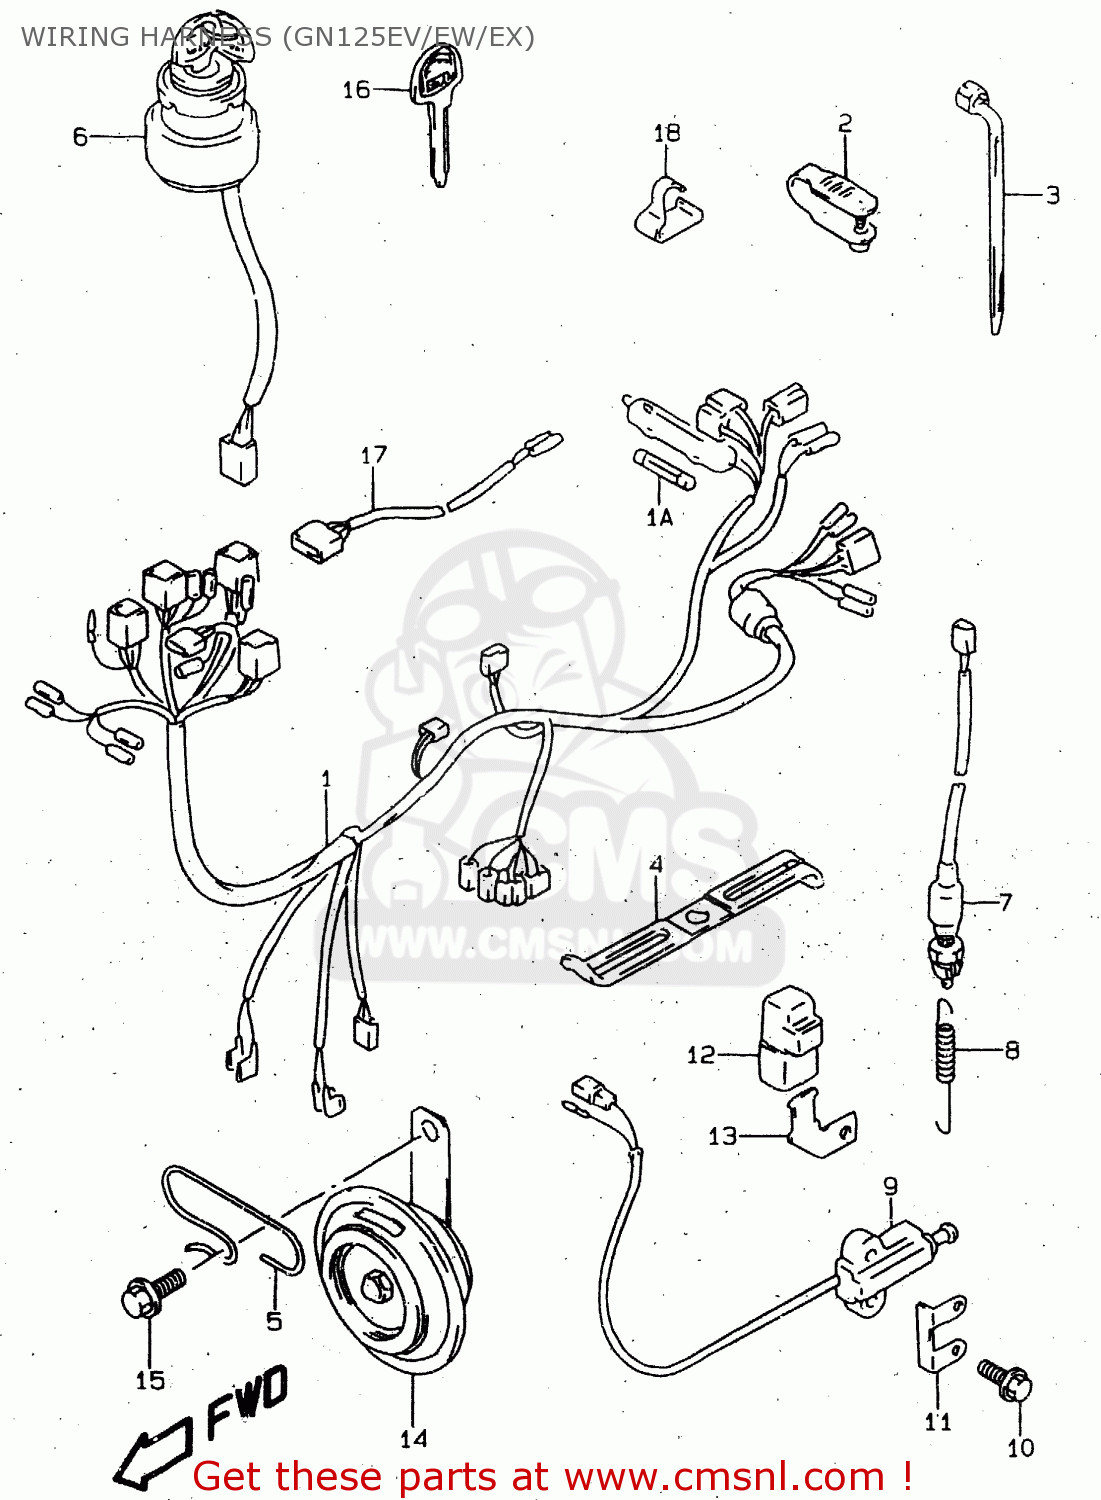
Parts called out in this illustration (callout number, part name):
1	HARNESS,WIRING
1A	FUSE(15A)
2	CLAMP,L:88
3	CLAMP L:165
4	CLAMP,STARTER MOTOR LEAD
5	CLAMP,WIRING HARNESS
6	SWITCH ASSY,IGNITION
7	SWITCH ASSY,STOP LAMP
8	SPRING
9	SWITCH ASSY,SIDE STAND
10	BOLT
11	PROTECTOR,SIDE STAND SWITCH
12	RELAY ASSY
13	BRACKET,SIDE STAND RELAY
14	HORN ASSY
15	BOLT
16	KEY,BLANK
17	WIRE,CLUTCH SWITCH LEAD
18	HOLDER,FUSE CASE
